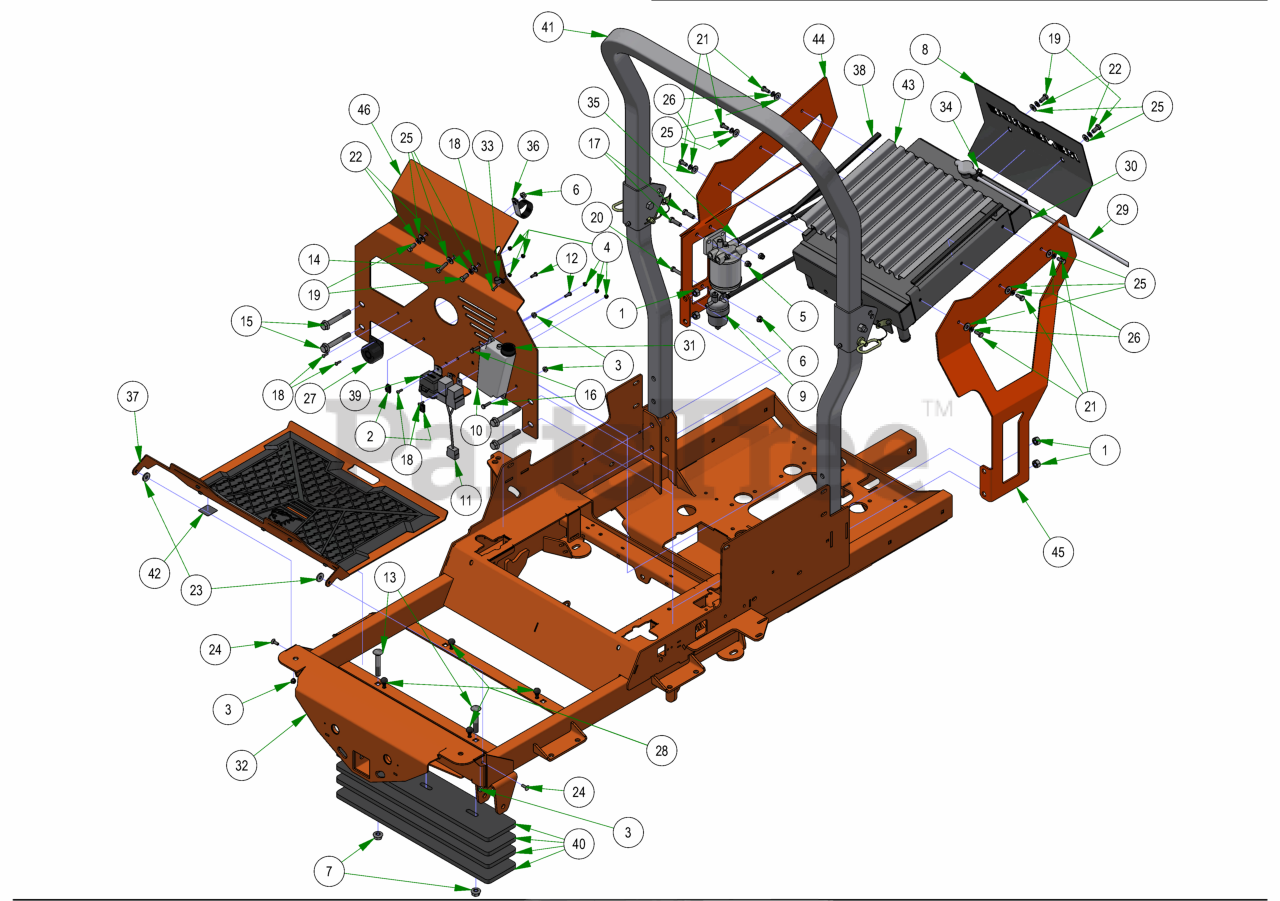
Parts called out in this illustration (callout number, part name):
1	1/2-13 HEX 2-WAY REVERSIBLE CENTER LOCKNUT Grade B ZINC
2	1/4-20 Cage Nut
3	1/4-20 NYL INSERT FLANGE LOCKNUT ZINC
4	10-24 NYLON INSERT LOCKNUT ZINC
5	3/8-16 NYLON INSERT LOCKNUT ZINC
6	5/16-18 NYLON INSERT FLANGE LOCKNUT ZINC
7	1/2-13 NYLON INSERT FLANGE LOCKNUT ZINC
8	2019 Diesel Upper Rear Cover - Black
9	24.7HP Perkins Engine, 403J-11
10	overflow Reservoir- 27Kaw & 28/35Hp Diesel
11	Diesel Relay Auto Shut Down Assembly
12	M6-1.0 X 16MM DIN 933 HEX TAP BOLT (CL 8.8) ZINC
13	1/2-13 x 3 Carriage Bolt Grade 5
14	5/16-18 X 1-1/4 HEX C/S (GR.5) ZC
15	1/2-13 X 3-1/2 HEX FLANGE BOLT (GR.8) ZINC
16	1/4-20 X 1 HEX CAP SCREW (GR.5) ZINC
17	3/8-16 X 1-1/4 HEX CAP SCREW (GR.5) ZINC
18	10-24 X 5/8 BUTTON SOCKET CAP SCREW 18-8 STAINLESS STEEL
19	3/8-16 X 3/4 HEX CAP SCREW (GR.5) ZINC
20	5/16-18 X 2-1/2 HEX CAP SCREW (GR.5) ZINC
21	5/16-18 X 3/4 HEX CAP SCREW (GR.5) ZINC
22	3/8 SPLIT LOCKWASHER ZINC
23	.360 ID X .983 OD X .120 THICK FLAT WASHER NYLON
24	1/4-20 X 3/4 CARRIAGE BOLT (GR.5) ZINC
25	5/16 USS FLAT WASHER (7/8 OD) ZINC
26	5/16 SPLIT LOCKWASHER ZINC
27	Heat Warning Piezo Buzzer
28	2023 Floor Board Rubber Bumper
29	2022 Renegade Diesel Fuel Line Assembly
30	2019 Diesel Radiator Kit
31	Reservoir Tank Cap-Overflow
32	2022 Horizontal Diesel Frame
33	3/8 Cable Clamp-Black Nylon
34	5/8 Hose Clamp
35	2 EAR CLAMP 12.5mm-15mm
36	Diesel Clamp 1 3/4" Vinyl
37	2024 R-Series Floorboard Assembly
38	Rubber Trim
39	2022 Renegade Diesel Wiring Harness
40	2019 Outlaw Counter Weight
41	2019 2X2 Folding ROPS
42	Patent Decal (Anti-Wobble)
43	Radiator Screen Diesel
44	2019 Diesel Radiator Mount - Right
45	2019 Diesel Radiator Mount - Left
46	2022 Diesel Radiator Mount
